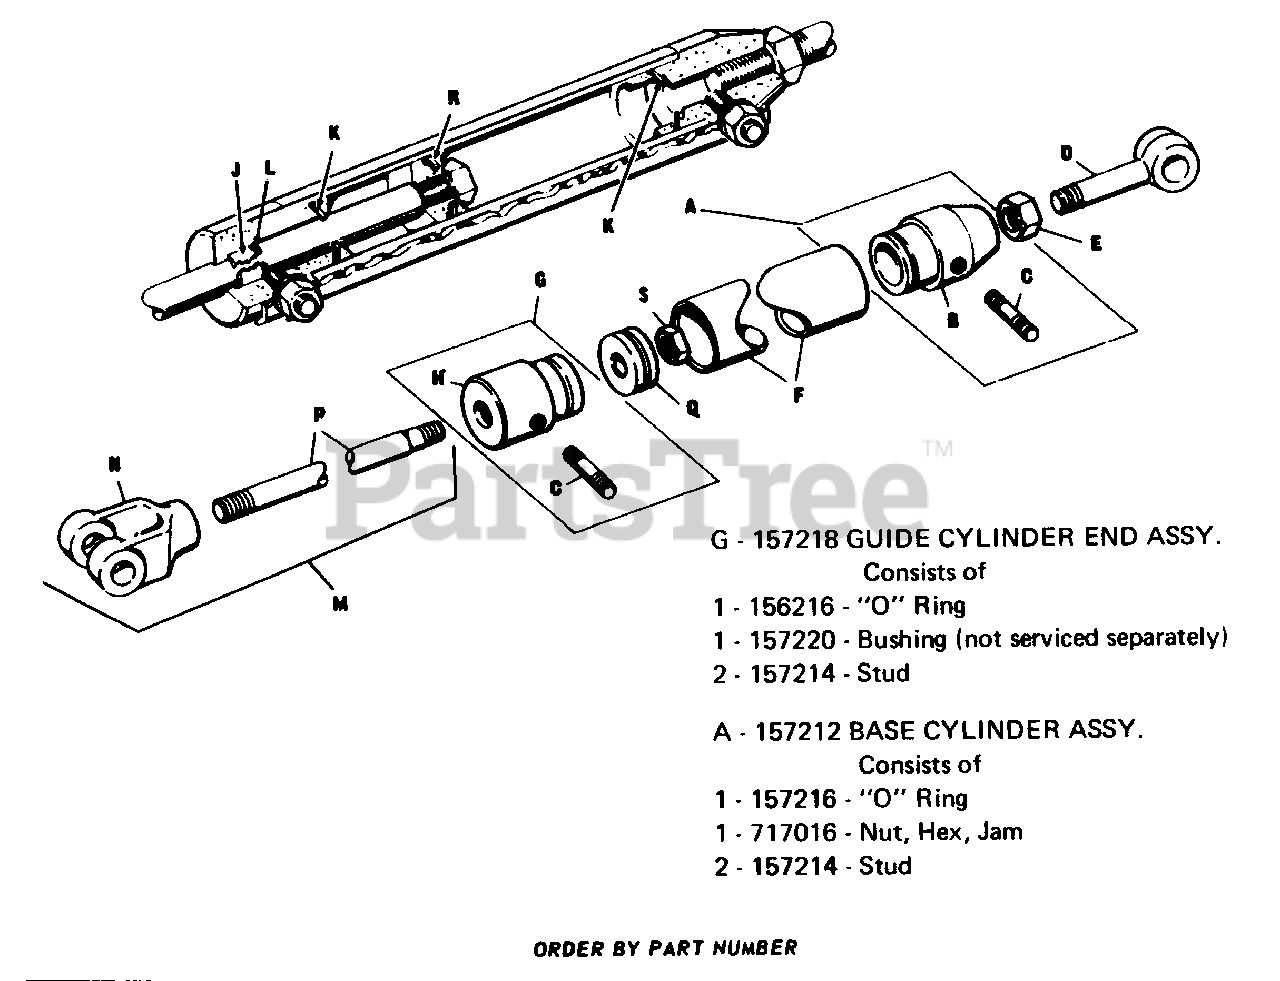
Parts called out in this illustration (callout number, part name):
A	Cylinder Base Sub-Assembly
B	Cylinder Base
C	Stud Bolt, 5/16"-18 x 7/8"
E	Jam Hex. Nut, 1/2"-20
G	Sub Assembly Guide
H	Cylinder End Guide
M	Yoke & Rod Sub-Assembly
P	Piston Rod
S	Full Hex. Nut
